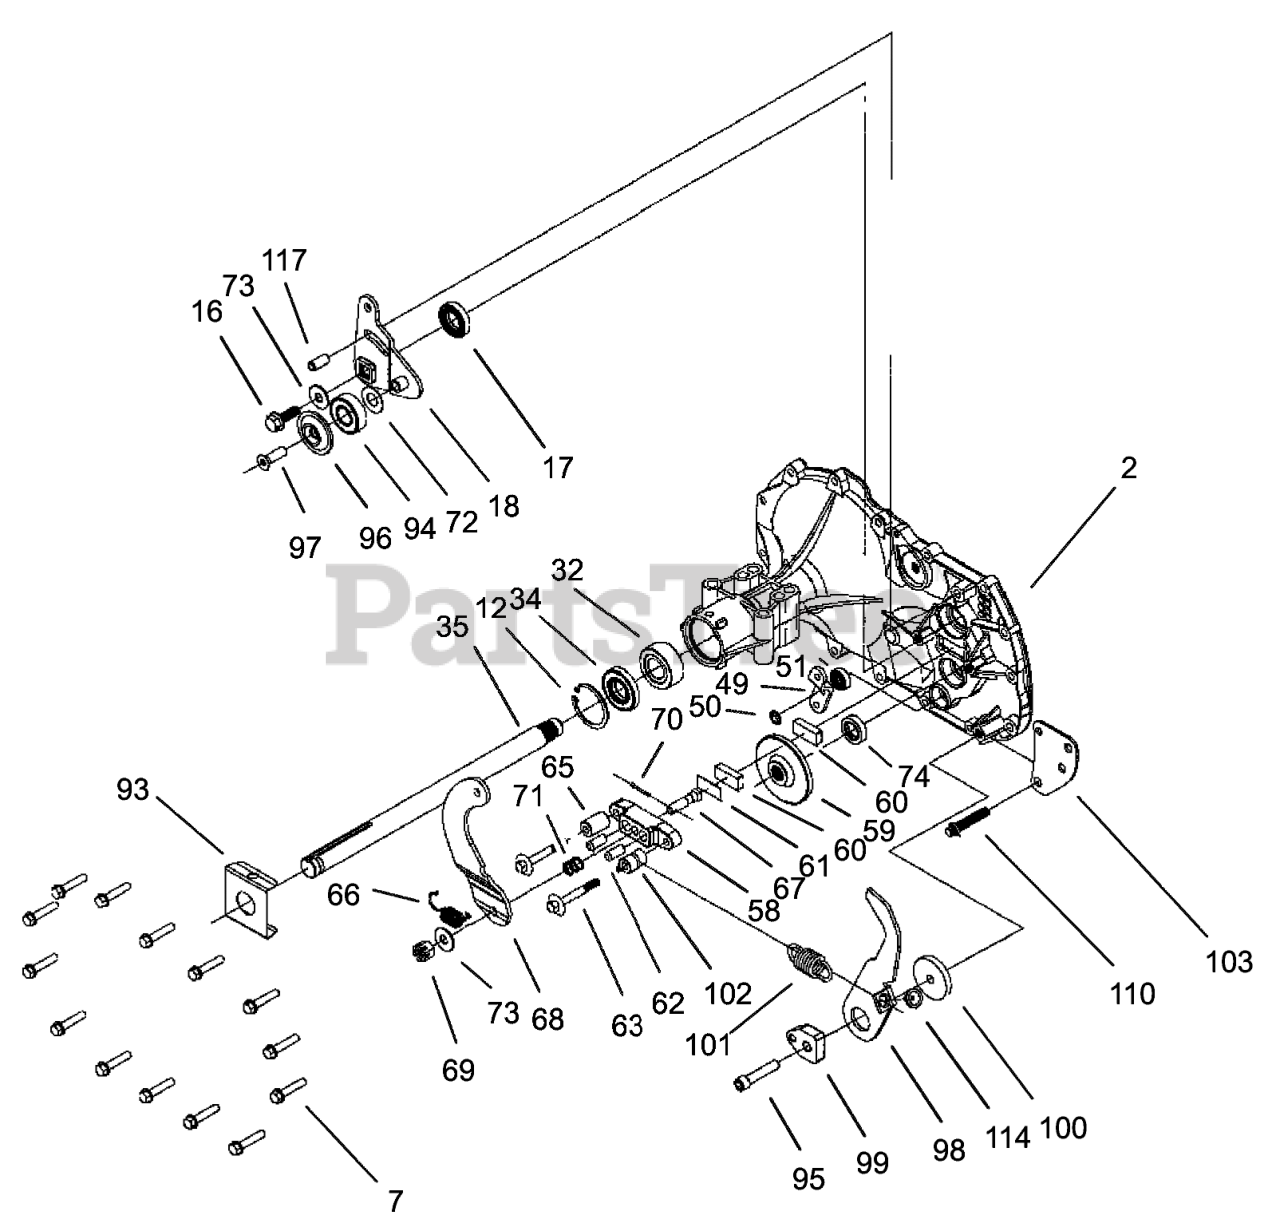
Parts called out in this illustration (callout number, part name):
2	SIDE HOUSING ASM
7	SCREW-HHF
12	RING-RETAINING
16	SCREW-HF
17	SEAL-LIP
18	ARM-CONTROL
32	BEARING-SLEEVE, OUTBOARD
34	SEAL-LIP
35	SHAFT-AXLE, RH
49	ARM-BYPASS
50	RING-RETAINING
51	SEAL-LIP
58	YOKE-BRAKE
59	ROTOR-BRAKE
60	PUCK-BRAKE
61	PUCK-PLATE
62	PIN-BRAKE
63	SCREW-HF
65	SPACER
66	SPRING-ARM, BRAKE (BIAS)
67	BOLT-SQH
68	ARM-BRAKE
69	NUT-CASTLE
70	PIN-COTTER
71	SPRING-BRAKE, ANTI DRAG
72	WASHER
73	WASHER
74	SEAL-OIL
93	CLIP-SPRING
94	BEARING
96	SPACER-LOCATING
97	SCREW-COUNTERSUNK
98	ARM-RETURN
99	PUCK-ADJUSTING
100	WASHER
101	SPRING-EXTENSION
102	SPACER
103	BRACKET-TORQUE
110	SCREW-TTH
114	GUIDE-SPRING
117	PIN-SPRING
